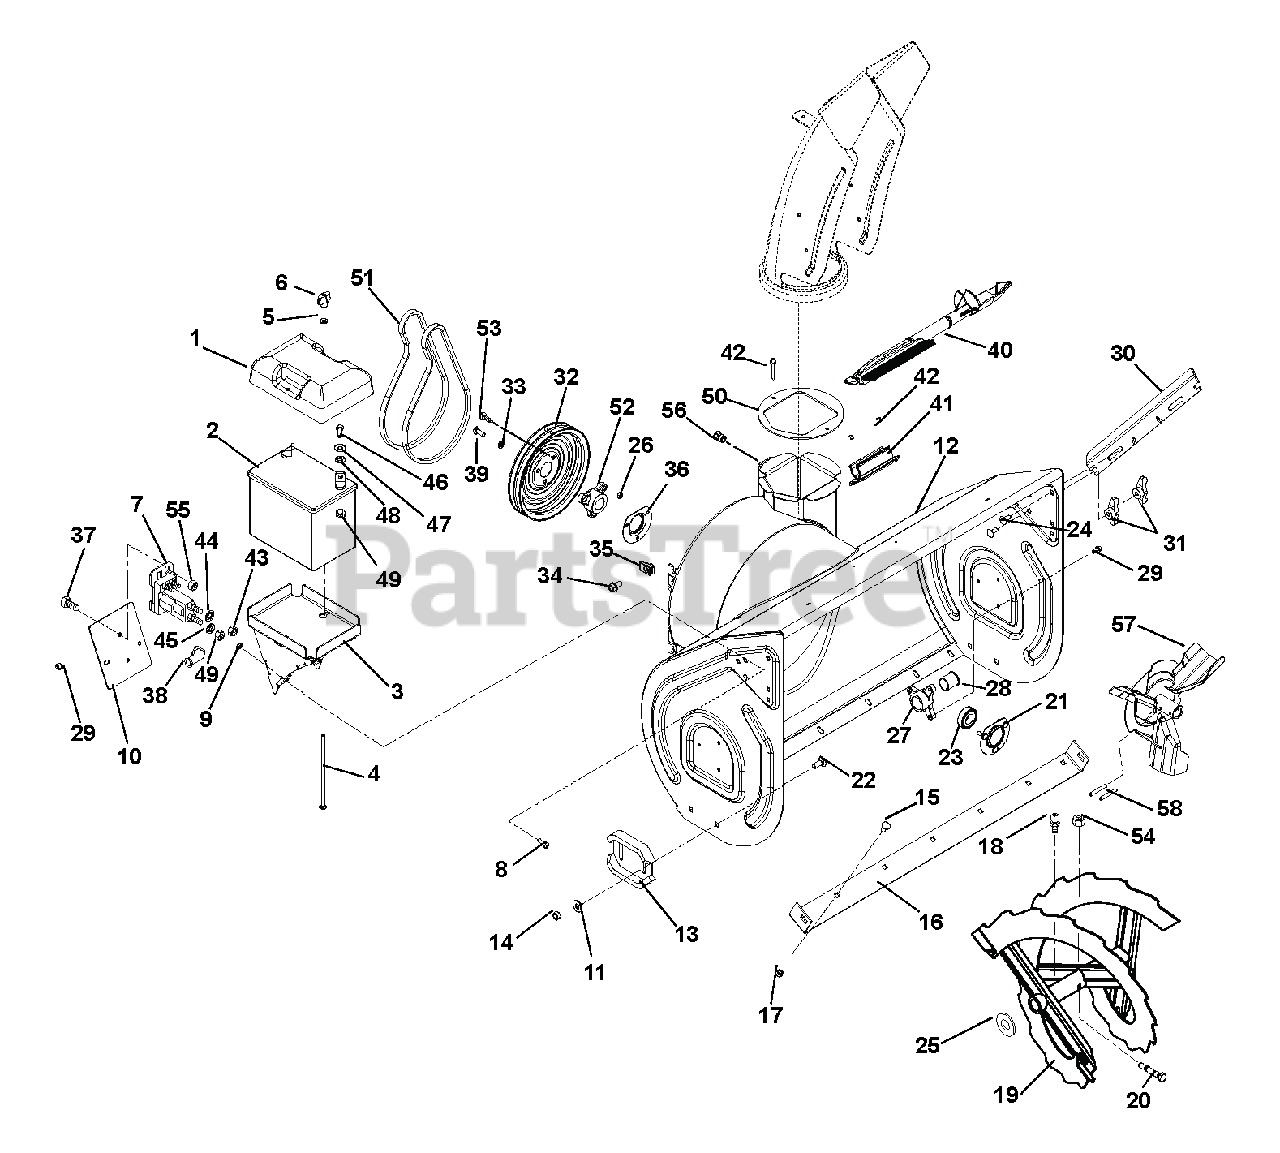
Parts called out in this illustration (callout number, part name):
1	COVER, BATTERY
3	TRAY, BATTERY-W/CLIPS
3	ASSY, BATTERY TRAY WITH CLIPS
4	@BLT-RDHDSQNK .25-20X7.00 G2YZ
5	@WSHR-FL-STL.281X.62X.065 YWZC
6	KNOB, WING - .25-20 UNC
7	SOLENOID
8	BLT-HEX .25-20X.75 HWH YZ GR5
8	NUT-RTNR .25-20X.56
9	NUT-RTNR .25-20X.56
10	COVER, SOLENOID
11	@WSHR-FL-STL.438X1.00X.083 YWZ
12	BLOWER HOUSING W/DECAL 28"
12	BLOWER HOUSING W/DECAL 32"
12	BLOWER HOUSING W/DECAL 32" BAT
12	BLOWER HOUSING W/DECAL 36"
13	RUNNER, SKID SHOE
14	@NUT-LK-CTR .38-16 YWZC
15	BOLT, MODIFIED HEAD CARRIAGE
16	BLADE, SCRAPER-28"
16	BLADE, SCRAPER-32"
16	BLADE, SCRAPER-36"
17	@NUT-LK-TOP-FLG .31-18 YWZC
18	ZERK,FITTING .25X.125 DRIVE IN
19	RAKE, LH-28"(1 ID X 15.75 OD)
19	RAKE, RH-28"(1 ID X 15.75 OD)
19	RAKE, LH-32"(1 ID X 15.75 OD)
19	RAKE, RH-32"(1 ID X 15.75 OD)
19	RAKE, LH-36" (1 ID X 15.75 OD)
19	RAKE, RH-36"(1 ID X 15.75 OD)
20	SHEAR BOLT SERVICE ASSEMBLY
21	BEARING FLANGE
22	@BLT-RDHDSHSQNK.38-16X1.0 G5YZ
23	BRG-BALL .876X1.75X.50 RSTFP
24	@BLT-RHDSSQNK .31-18X.75 G5YZ
25	WSHR-FL-STL 1.010X1.505X.062YZ
26	@NUT-LK-CTR .25-20 YWZC
27	BUSHING, RAKE SHAFT 1"
28	BSHG-FLG SPLIT NYLINER 1.0" HP
29	SCR-TAP .25-20X.50 HWH TR YWZ
30	CUTTER, DRIFT
31	KNOB,WING .31-18 UNC NYL/TALC
32	PULLEY, SPIN FORM DUAL GROOVE
33	WSHR-LK .312X.097 HVY YWZC
34	BLT-SERHFWH .38-16X.75 YWZC
35	NUT-RTNR .375-16X.37
36	BEARING FLANGE
37	@BLT-HEX .25-20X.50 GR5 YWZC
38	BOOT, EYELET TERMINAL
39	BLT-HEX .31-24X.75 YWZC GR5
40	DEVICE, SNOW CLEAN OUT W/BRUSH
41	MOUNT, SNOW CLEAN OUT
42	RVT-POP .187 YZ
43	NUT-JAM .31-24 YWZC
44	WSHR-LOCK INT .31 YWZC
45	@WSHR-LK-EXT.262X.502X.026YWZC
46	@BLT-HEX .25-20X.75 GR5 YWZC
47	WSHR-FL-STL .265X.50X.087YWZC
48	@WSHR-LK .25X.062 REG YWZC
49	@NUT-HEX .25-20 YWZC
50	BAFFLE, DISCHARGE NECK
51	V-BELT, HA-RAW EDGE (SET)
52	PULLEY HUB, D-BORE .87 PRO
53	@SCR-TAP .31-18X.50 HWH TR YWZ
54	@NUT-LK-CTR .31-18 YWZC
55	@NUT-LK-CTR .25-20 YWZC
56	NUT, THREADED INSERT .38-16
57	IMPELLER, 3 BLADE-14"
58	PIN-ROLL .250X1.75
